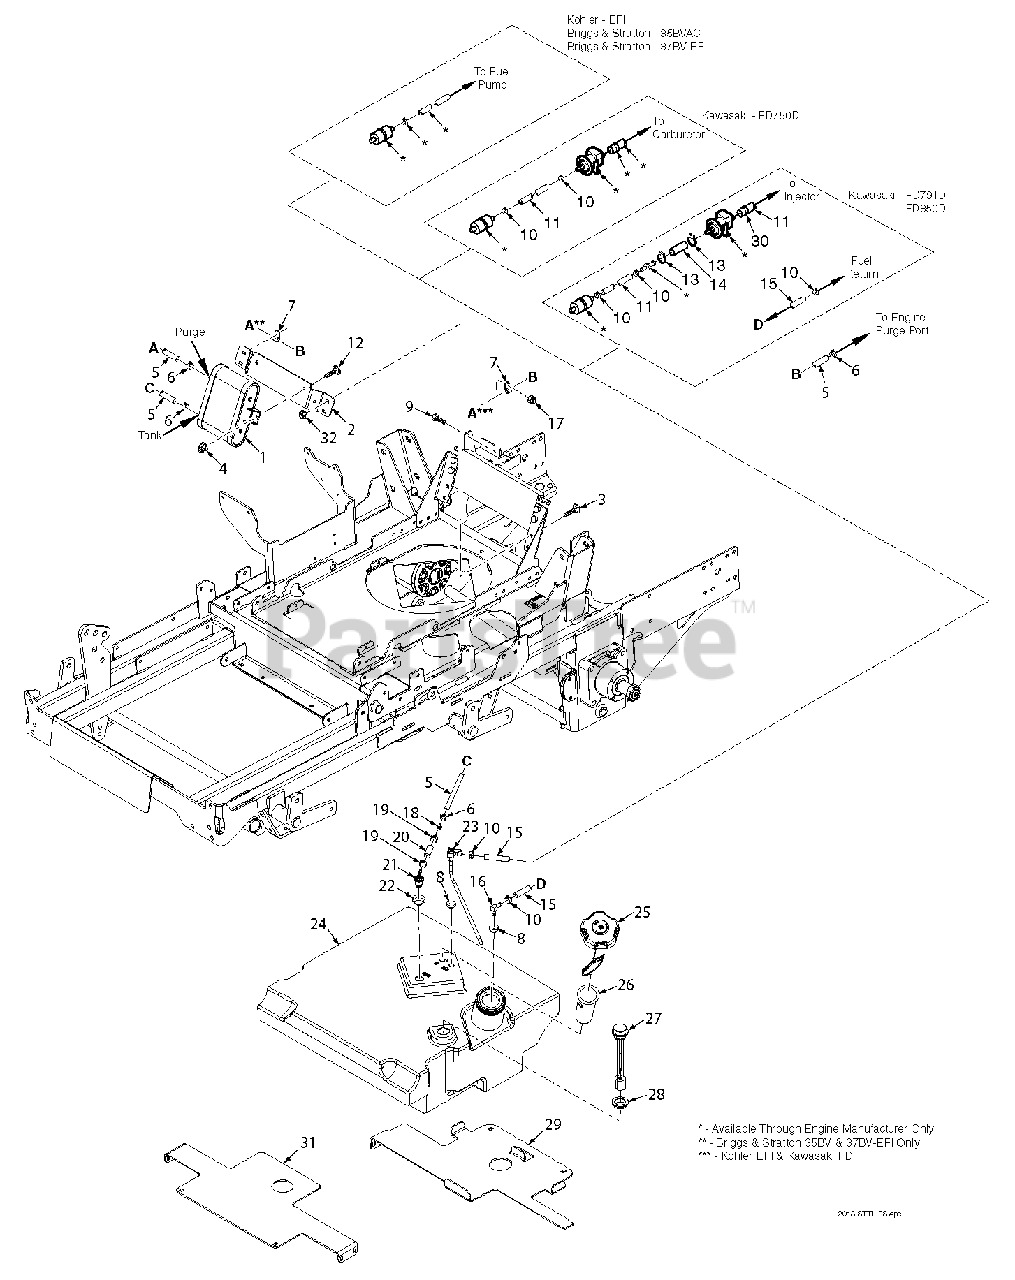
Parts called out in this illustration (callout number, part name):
1	Canister, 1.0 Liter
2	Bracket, Carbon Canister
3	Bolt, Carriage 1/4-20 x 3/4"
4	Nut, Flange Elastic Stop 5/16-18
5	Hose, 3/16 (order by inch)
6	Clamp, Vapor Recovery Hose 3/16
7	Clamp, Cable - .375 Dia.
8	Bushing, .56 Dia. Viton
9	Bolt, Hex Head 5/16-18 x 3/4"
10	Clamp, Fuel Return
11	Fuel Hose, 5/16 I.D. Non-Perm (order by inch)
12	Bolt, Carriage 5/16-18 x 3/4"
13	Clamp, .87 Max. Dia.
14	Fuel Hose, 1/2 I.D. Non-Perm (order by inch)
15	Fuel Hose, 1/4 I.D. Non-Perm (order by inch)
16	Return Fitting
17	Nut, Elastic Stop 5/16-18
18	Mender, 1/4 x 3/16 w/.02 Hole
19	Clamp, Fuel Hose 7/32 I.D.
20	Hose, Vapor Recovery 1/4 (order by inch)
21	Remote Vent
22	Grommet, Viton
23	Valve, Fuel Shutoff
24	Fuel Tank Assy. - Kawasaki DFI
24	Fuel Tank Assy.
25	Fuel Cap, Tethered
25	Fuel Cap, Tethered (CA)
26	Tube, Fuel Tank Insert - 8"
27	Fuel Gauge Assy., 8"
28	Seal, Fuel Gauge
29	Rear Support, Fuel Tank
30	Clamp, .69 Dia.
31	Front Support, Fuel Tank
32	Nut, Serrated Flange 1/4-20
